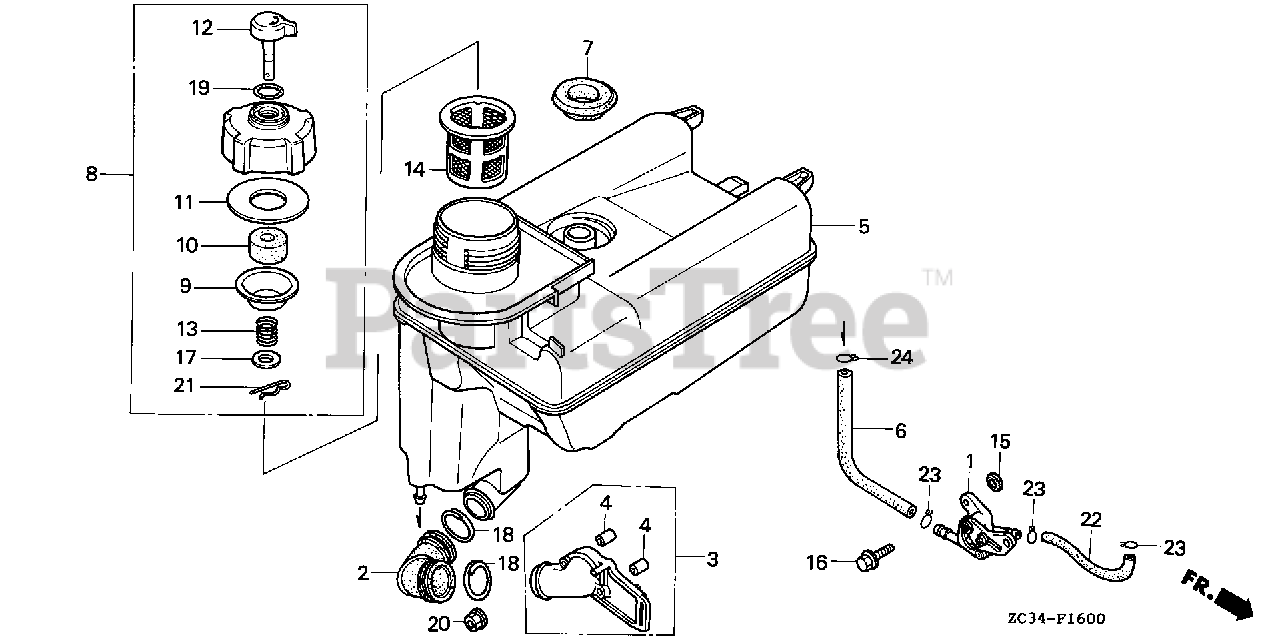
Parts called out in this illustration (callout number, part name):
1	PETCOCK ASSY.
2	TUBE, AIR CLEANER CONNECTING
3	JOINT, AIR IN.
4	COLLAR, IN. JOINT
5	TANK, FUEL
6	TUBE, FUEL
7	RUBBER, CONNECTOR SEALING
8	CAP ASSY., FUEL TANK
9	INNER, FUEL CAP
10	SPONGE, FUEL CAP BREATHER
11	GASKET, FUEL CAP
12	VALVE, BREATHER
13	SPRING, FUEL CAP
14	FILTER, FUEL
15	GASKET, MUFFLER PROTECTOR
16	BOLT, FLANGE (5X14)
17	WASHER (6MM)
18	CLIP (28MM)
19	O-RING (13.8X2.4)
20	NUT, FLANGE (6MM)
21	PIN, LOCK (6MM)
22	BULK HOSE, FUEL (4.5X3000) (4.5X65)
23	CLIP, TUBE (B8)
24	CLIP, TUBE (C9)
